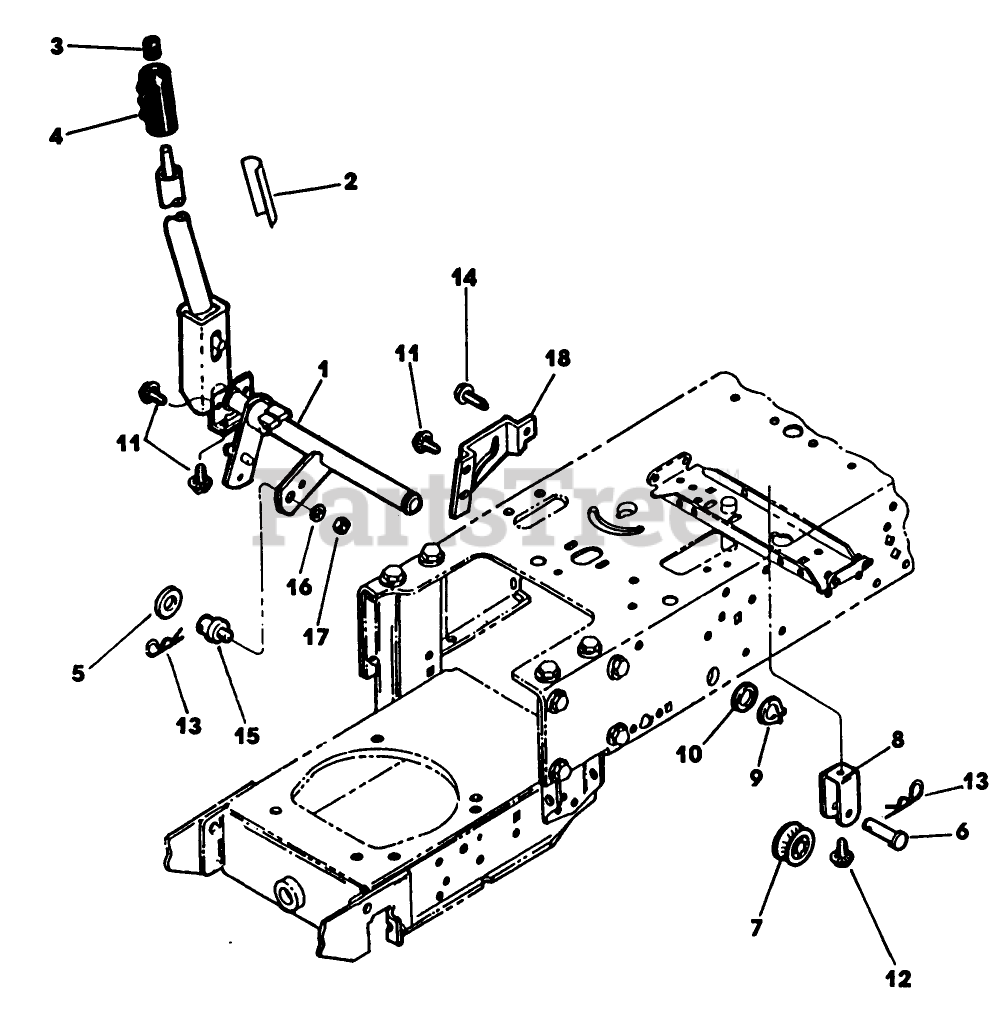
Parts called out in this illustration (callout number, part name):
1	LIFT SHAFT&DECL AY *B
2	STICKER-LIFT
3	TIP-ROD
7	SPOOL - CABLE
9	RING-RETAINING
10	WASHER
13	PIN-HAIR
16	WASHER
17	NUT
